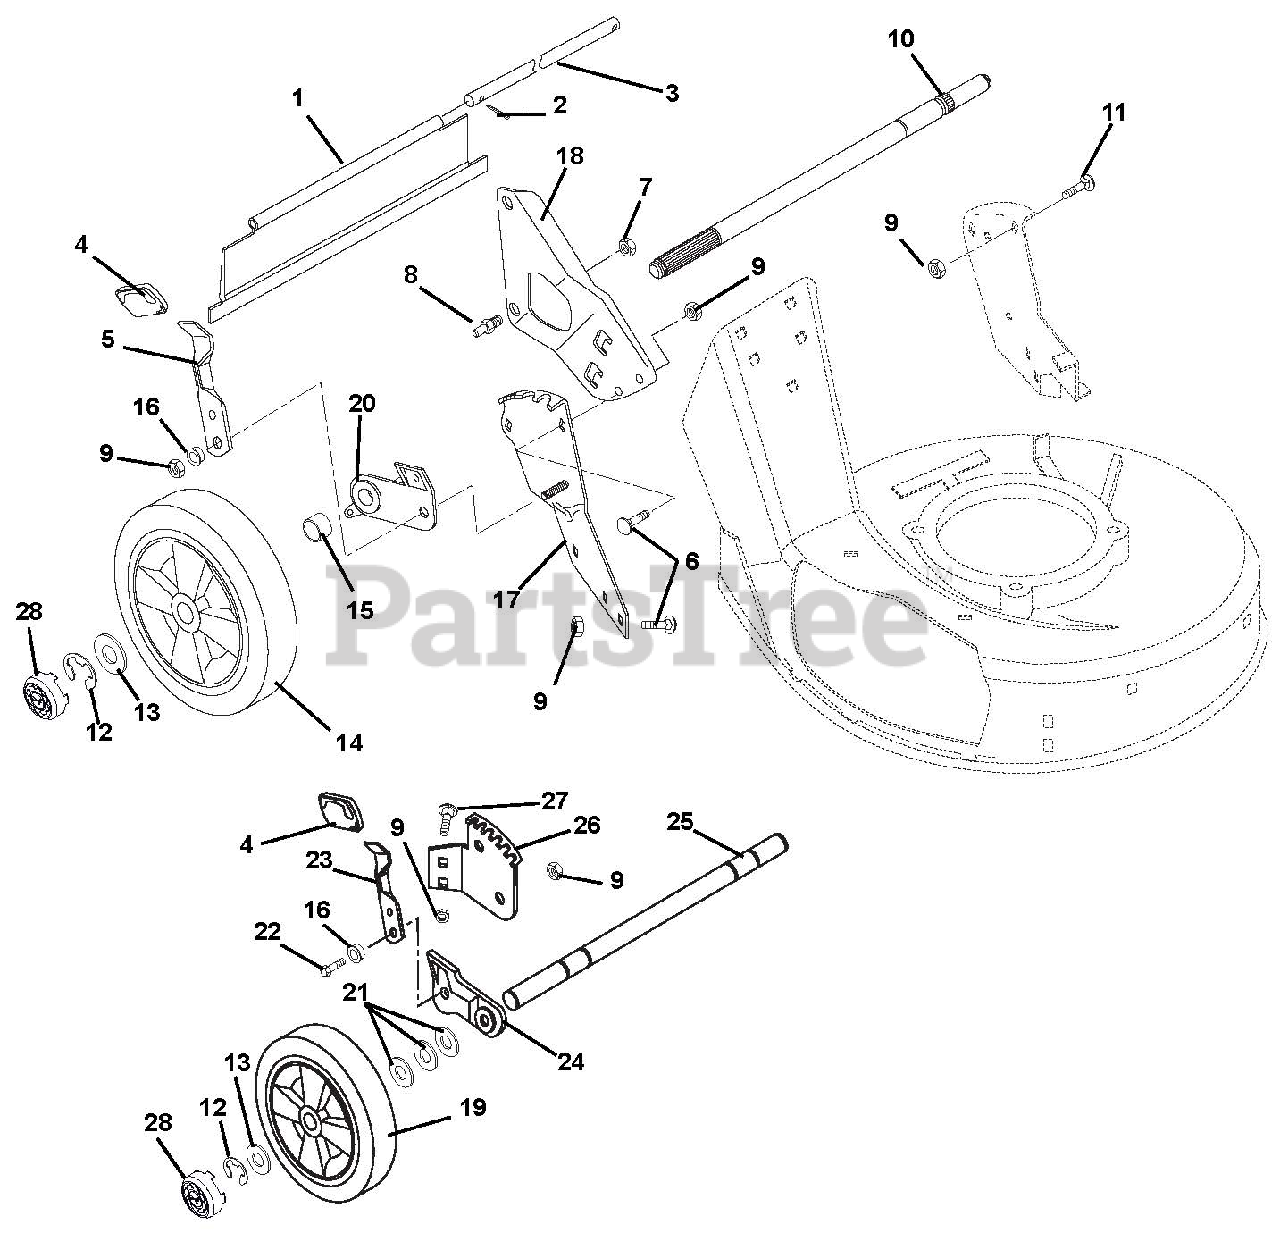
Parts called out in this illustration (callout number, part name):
1	REAR PROTECTIVE GUARD, S.P.
2	@PIN-CTR .06X.50 EXTPRSQCT YWZ
4	KNOB
5	LEVER, HEIGHT ADJUSTMENT
6	@BLT-RHDSSQNK .31-18X.62 G5YZ
7	@NUT-LK-CTR .38-16 YWZC
8	HANDLEBAR STUD
9	@NUT-LK-TOP-FLG .31-18 YWZC
10	REAR AXLE,5/8 DIA
11	@BLT-RHDSSQNK .31-18X1.00 G5YZ
12	RG-RTNG-EXT .500X.042 (E)
13	WSHR-FL-STL .505X.880X.072 YWZ
14	WHEEL, ASSEMBLY CLASSIC LM- LH
14	WHEEL, 10.3" O.D X 2" W RHS
15	SPACER TUBE, SELF PROPEL
16	BSHG-FLG .32X.500X.344X.880
17	QUADRANT, REAR LH
17	QUADRANT, REAR RH
18	RH HANDLEBAR MTG. BRKT
18	LH HANDLEBAR MTG. BRKT
19	WHEEL, 7.5" OD X 1.75" WIDE
20	REAR BRACKET & BEARING ASSY LH
20	REAR BRACKET & BEARING ASSY RH
21	WSHR-FL-STL .52X.827X.062 YWZC
22	@BLT-HEX .31-18X1.00 GR5 YWZC
23	FRONT HEIGHT ADJUSTMENT LEVER
24	LEFT ADJUSTOR BRACKET ASSEMBLY
24	RIGHT ADJUSTOR BRACKET ASSEMBL
25	FRONT AXLE
26	FRONT QUADRANT, LH
26	FRONT QUADRANT, RH
27	@BLT-RDHDSQNK .31-18X.50 G5YZ
28	HUB CAP, LM WHEEL
29	@NUT-LK-CTR .31-18 YWZC
